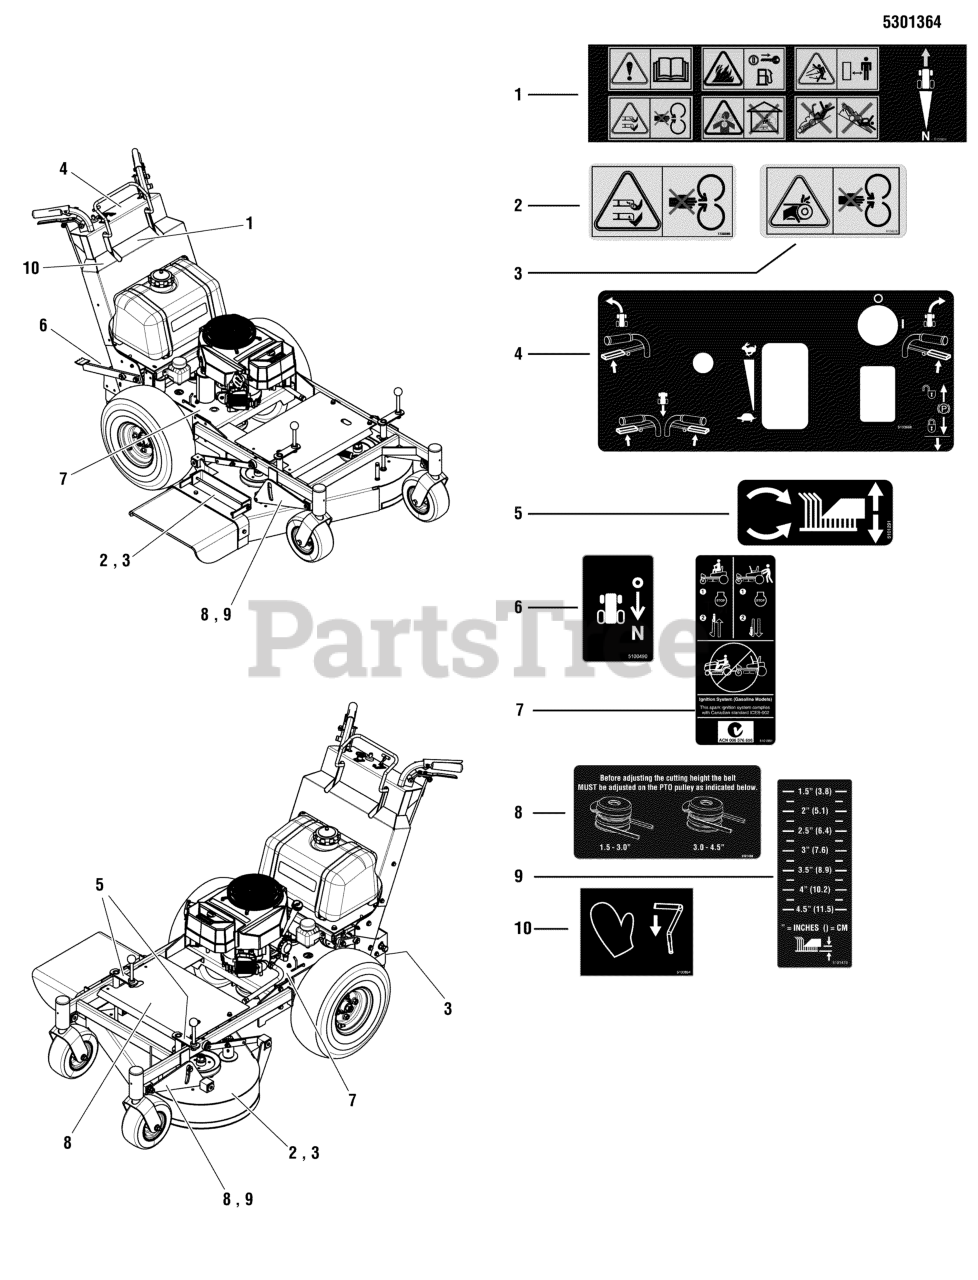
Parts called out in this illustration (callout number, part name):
1	DECAL, CCW, CE
2	DECAL, DANGER ROTATING BLADE SYMBOLS
3	DECAL, CE DANGER
4	DECAL, CONTROL PANEL, WB
5	DECAL, CUT HEIGHT, SPDD
6	DECAL, PEDAL
7	DECAL, TRANSAXLE RELEASE
8	DECAL, BELT LOCATION, PTO, SW20
9	DECAL, CUT HEIGHT, SW-20
10	DECAL, OPC, CCW
